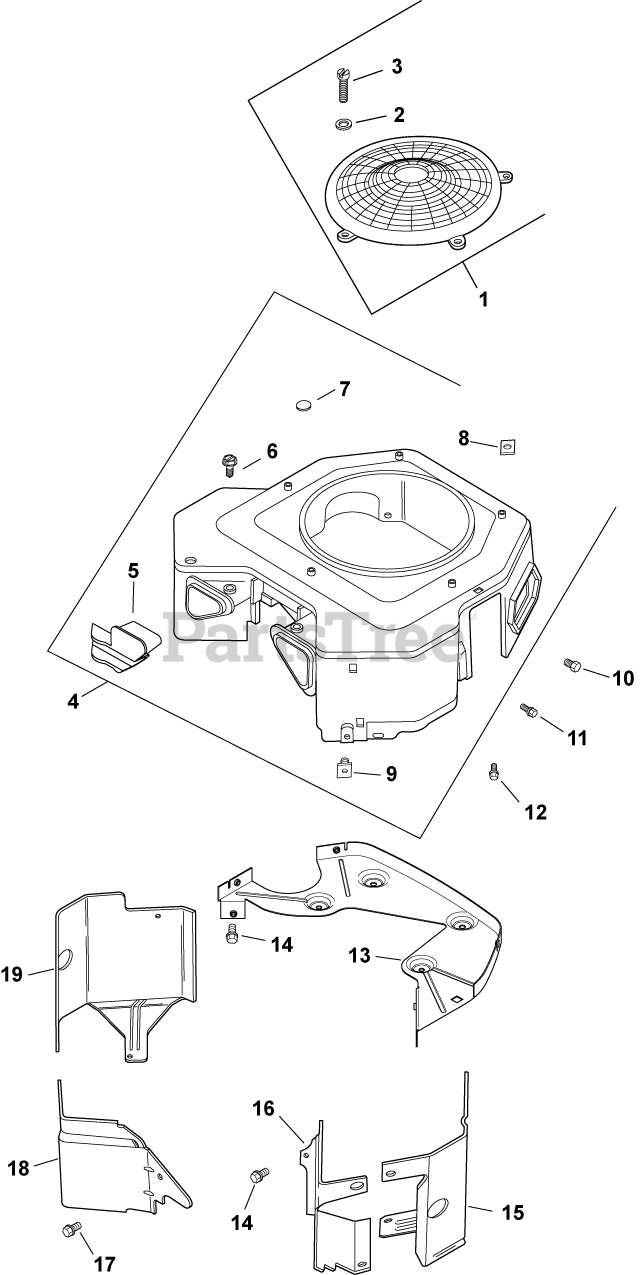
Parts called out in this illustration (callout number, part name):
1	KIT, FIXED GUARD
2	WASHER, FLAT 7/32"
3	SCREW, LBD SCKT PAN M5X0.8X10
4	KIT, BLOWER HOUSING ASSY-(#24027492S)
5	COVER, BLOWER HOUSING-USE 24 096 119-S
6	SCREW, WSH HD TAP #8-18X1/2"
7	PLUG, BUTTON 9/16
8	NUT, PLASTIC
9	NUT, PLASTIC (KM)-USE 25 100 37-S
10	SCREW - USE M-545016-S
11	SCREW,FLG THD FRM M5X0.8X16-(#25086398S)
12	SCREW, FLG THD FRM M5X.8X20-(#25086399S)
13	PLATE, BACKING-USE 24 146 59-S
14	SCREW,FLG THD FRM M6X1.0X16-(#25086397S)
15	KIT, CYL BAFFEL #2 SIDE
16	BAFFLE, VALLEY #2 SIDE-USE 24 063 94-S
17	SCREW, FLG THD FRM M5X.8X10
18	BAFFLE, VALLEY (CV)-USE 24 063 93-S
19	KIT, CYL BAFFEL #1 SIDE
